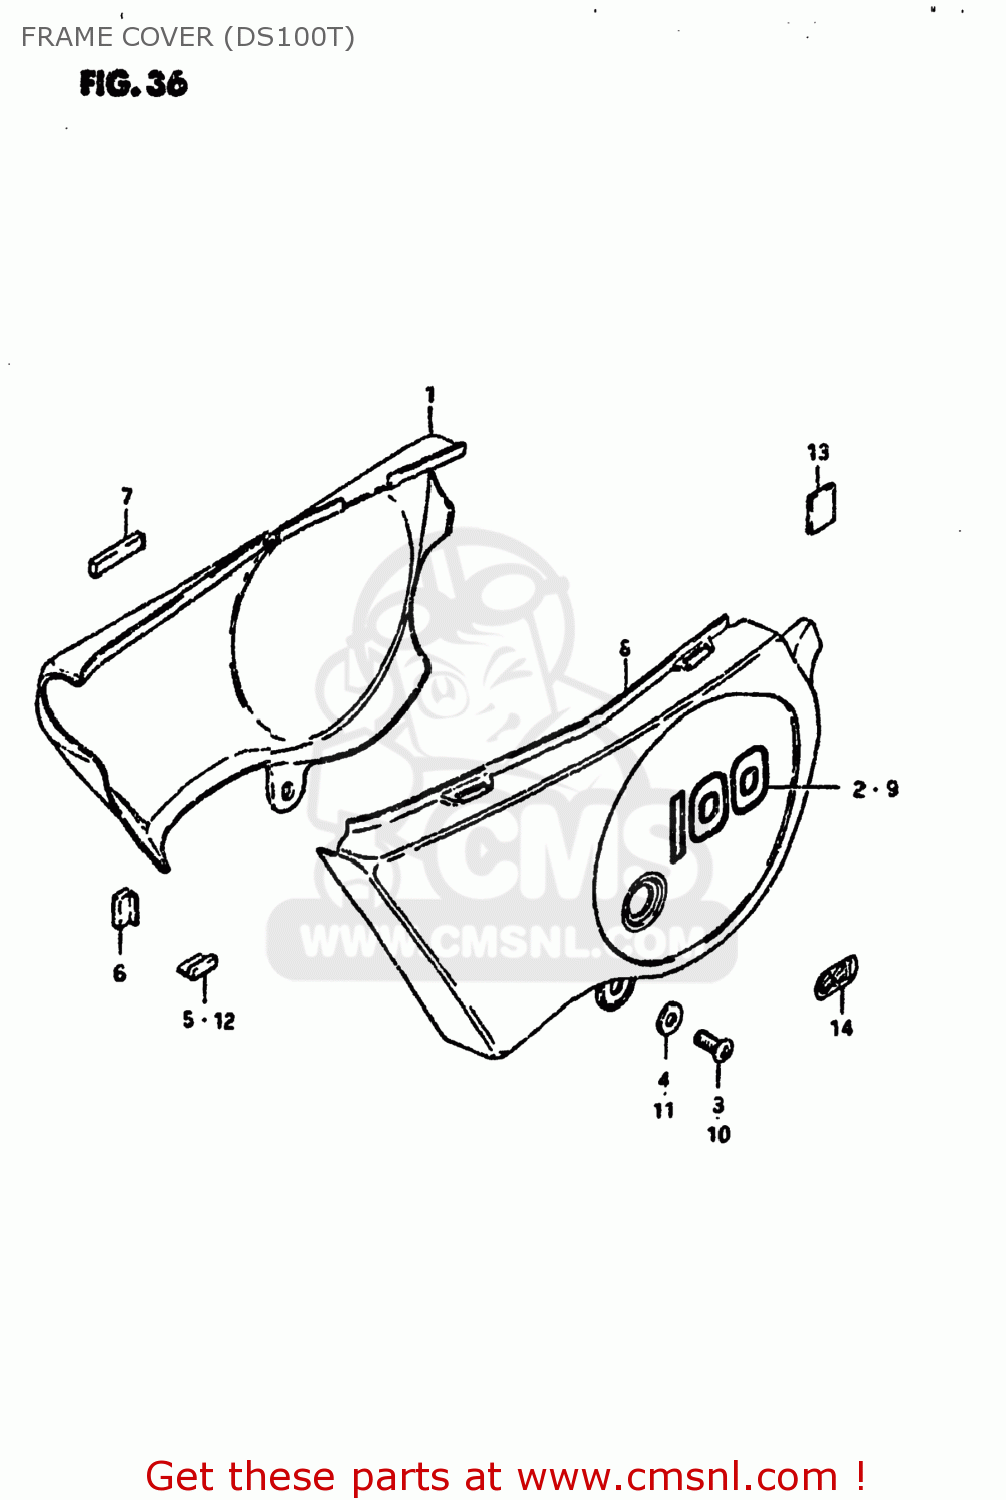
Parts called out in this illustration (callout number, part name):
1	COVER,FRAME,RIGHT
2	EMBLEM
3	SCREW 6X12
4	WASHER
5	CUSHION,FRAME COVER
6	CUSHION,FRAME COVER
7	CUSHION,FRAME COVER
8	COVER,FRAME,LEFT
9	EMBLEM,FRAME COVER
10	SCREW 6X12
11	WASHER
12	CUSHION,FRAME COVER
13	PROTECTOR(170X95X3.0)
14	EMBLEM,CCIS
